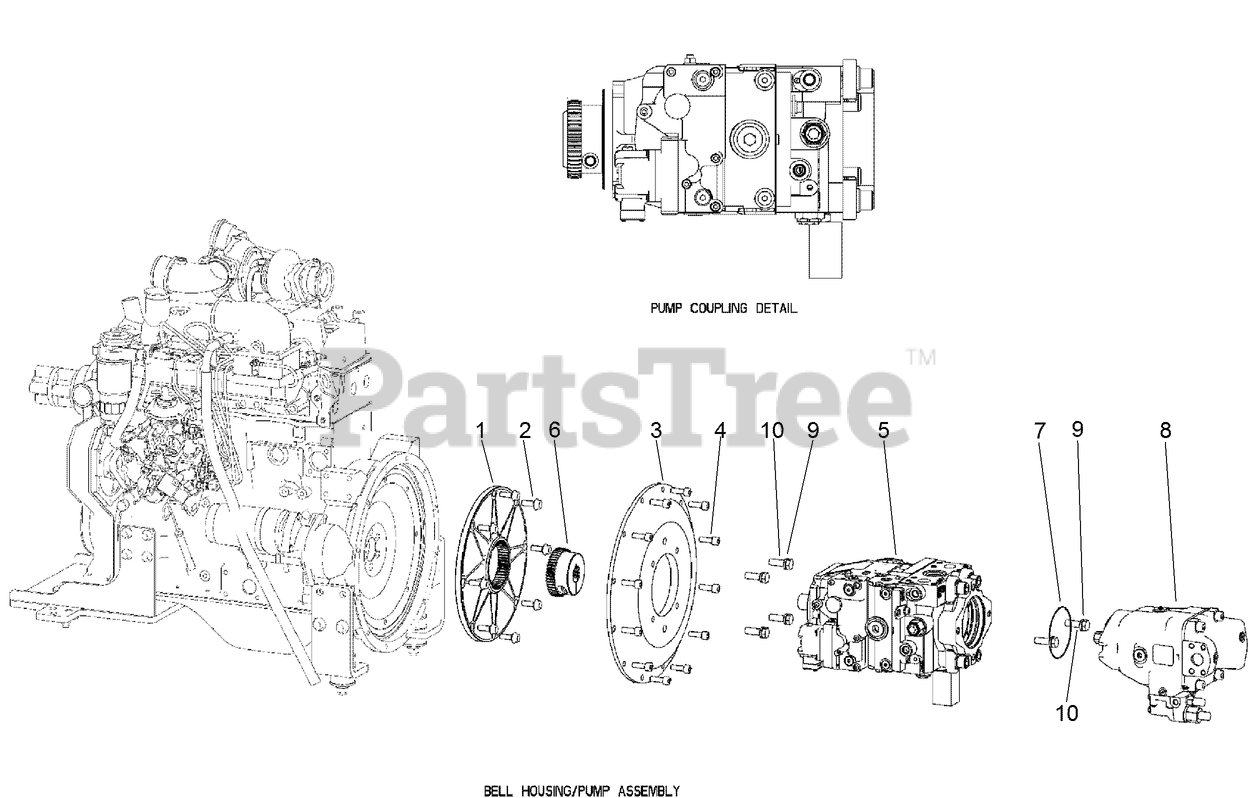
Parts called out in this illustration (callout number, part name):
1	COUPLING-DRIVE
2	SCREW-HH
3	MOUNT - Pump
4	SCREW-HSH
5	HYD HYDROSTAT PUMP ASM
6	HUB-STEEL
7	O-RING - .062 x 4.00 in Class 5
8	HYD LOAD SENSE PISTON PUMP ASM
9	WASHER-Spring Lock Reg 1/2 ZND
10	SCREW-HH
